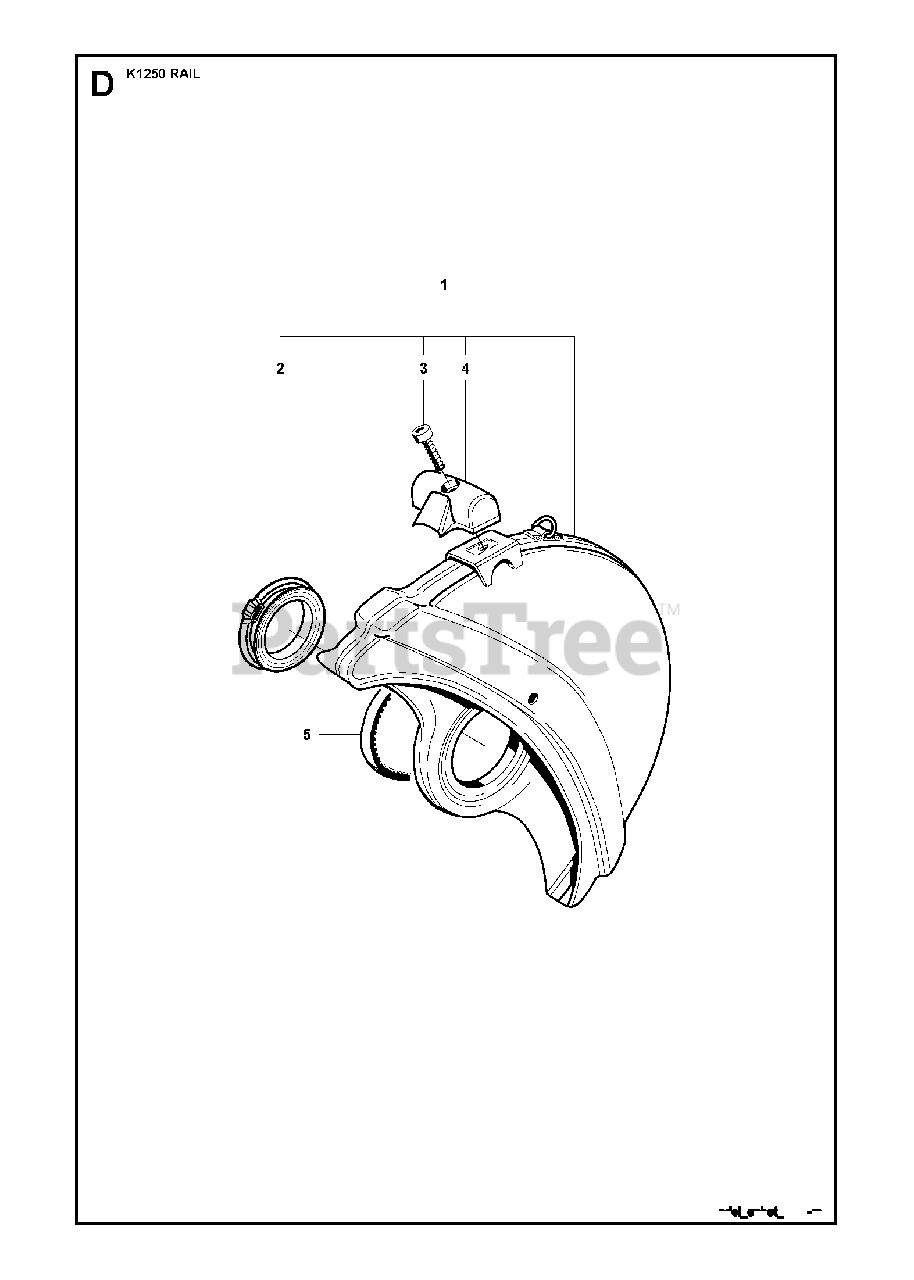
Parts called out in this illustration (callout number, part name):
1	WHEEL GUARD ASSY14" Incl. 2, 3, 4
1	WHEEL GUARD16" Incl. 2, 3, 4
3	SCREW IHSCM
5	BELT
